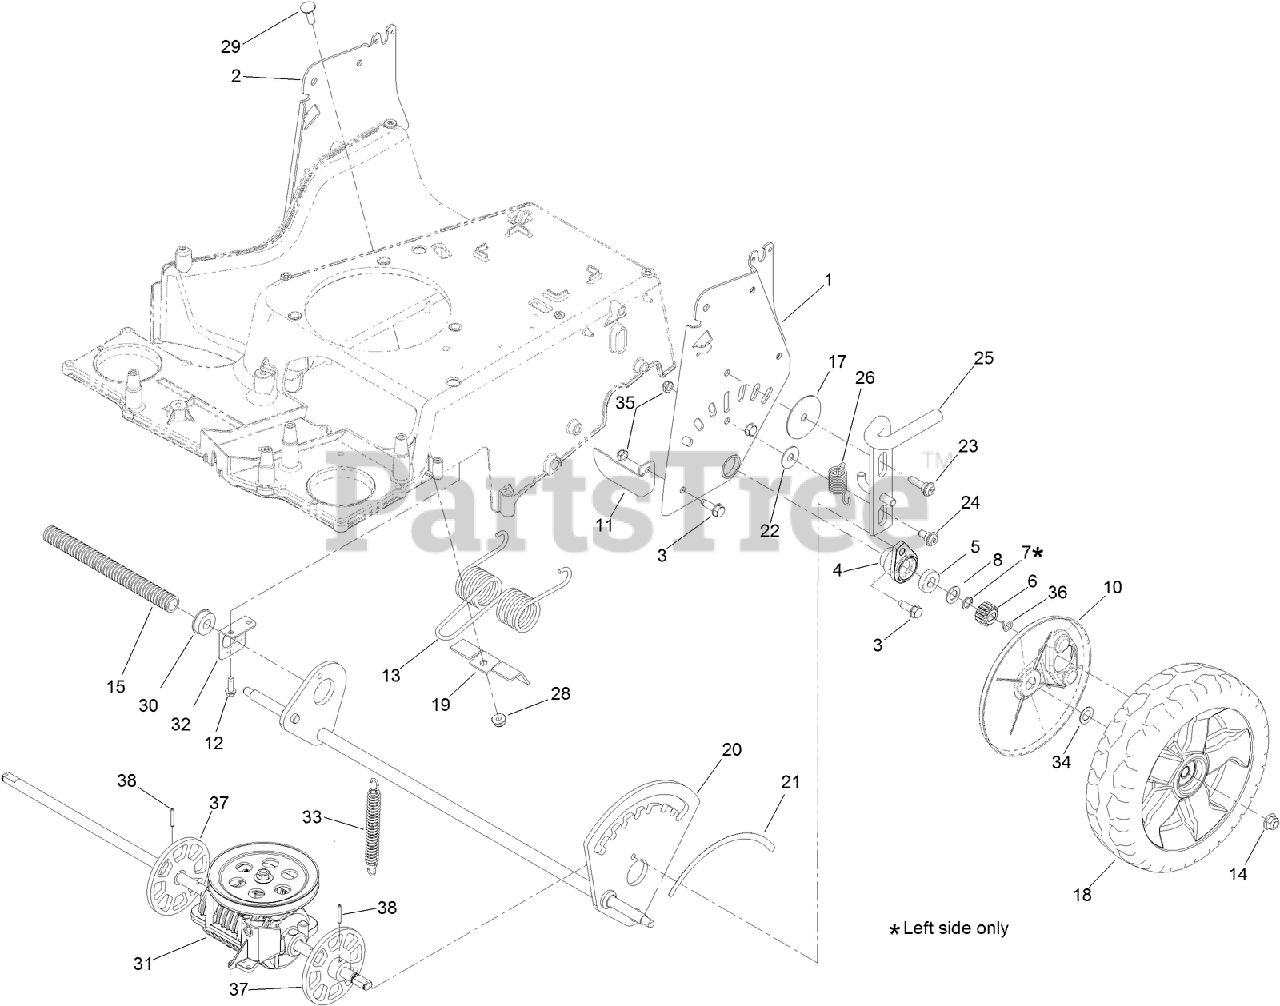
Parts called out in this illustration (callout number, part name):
1	LH HOC PLATE ASM
2	RH HOC PLATE ASM
3	SCREW-HWHTF
4	RETAINER-BEARING
5	BEARING-BALL
6	GEAR-PINION, 15T
7	RING-RETAINING
8	WASHER-THRUST
10	COVER-GEAR
11	BRACKET-STOP
12	SCREW-HWHTF
13	SPRING-TORSION
14	NUT-HF, NI
15	CONDUIT-CONVOLUTED
17	WASHER-PLAIN
18	WHEEL ASM (W/GEAR)
19	BRACKET
20	AXLE-REAR
21	DECAL-HOC, REAR
22	WASHER
23	SCREW-SHOULDER, BHTF
24	BOLT-SHOULDER
25	LOCK-HEIGHT, ADJUST
26	SPRING-EXTENSION
28	NUT-HF, NI
29	BOLT-CARR
30	BEARING-BALL
31	TRANSMISSION
32	MOUNT-BEARING
33	SPRING-EXTENSION
34	WASHER-PLAIN
35	NUT-LOCK, NI
36	PIN-SNAP
37	ROTOR ASM
38	PIN-ROLL
